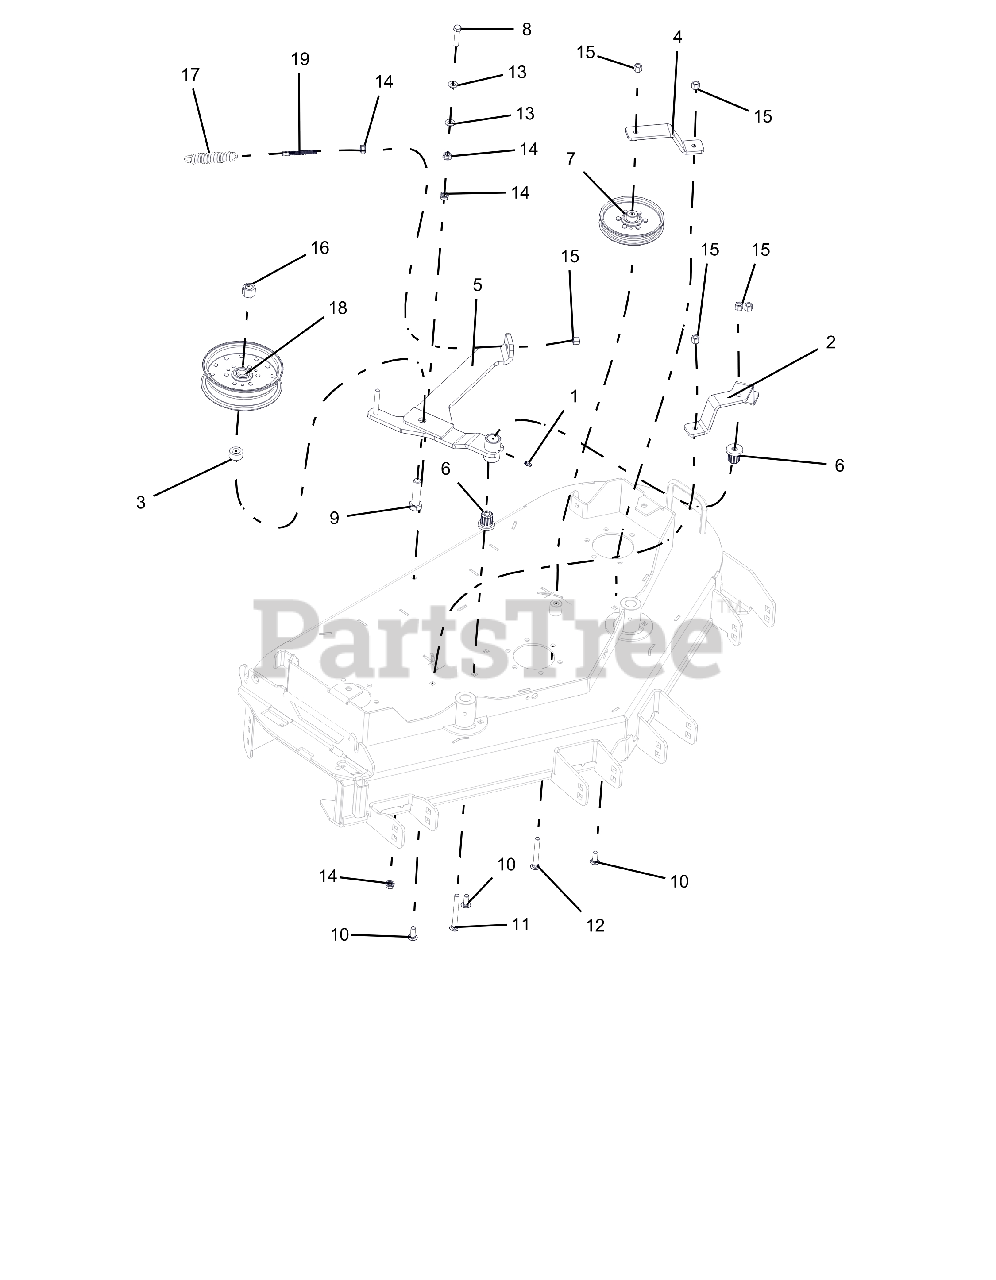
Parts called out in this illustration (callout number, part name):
1	FTG, 1/4-28 STRGT GREASE ZERK
2	STRAP, IDLER 48 FLWLK-BLACK
3	BUSHING, .688 X 1.13 X .55
4	STRAP, IDLER 48/52 WALK-BLACK
5	WLDT, IDLER ARM 52/48 FLWLK-BLACK
6	BRG, FLG M10XM25XM27 FLUTED
7	PULLEY, FLAT IDLER .500 X .375 W/BRG
8	BLT-HEX .38-16X1.75 GR5 YWZC
9	BLT-HEX .62-11X2.50 GR5 YWZC
10	BLT-RDHDSHSQNK.38-16X1.0 G5YZ
11	BLT-RDHDSQNK .38-16X3.50 G5 YWZC
12	BLT-RDHDSQNK .38-16X3.00 G5 YWZC
13	WSHR-FL-STL.406X.812X.065 YWZ
14	@NUT-SPNLK-FLG .375-16 YWZC
15	NUT-LK-NYL .38-16 YWZC
16	NUT-LK-NYL .625-11 YWZC
17	SPRING, EXT .875X.125X4.25 Y
18	PULLEY, FLAT IDLER 6.00 X .635
19	ROD, THREADED ADJUSTMENT
